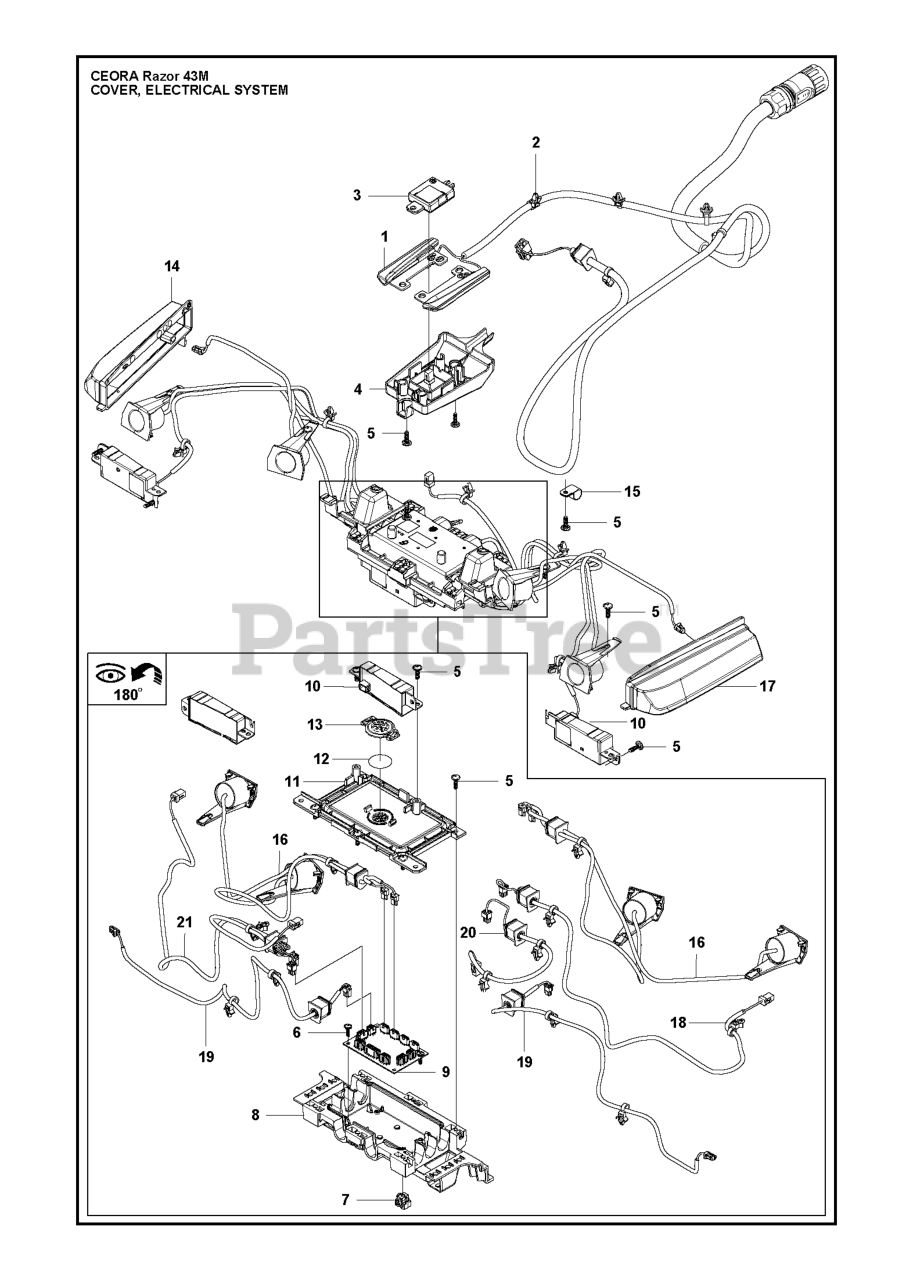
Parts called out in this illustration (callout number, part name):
1	WIRING ASSY
2	TIE WRAP CABLE TIE W ARROW MOU
3	HOUSING ASSY MAGNETIC SENSOR
4	HOLDER CHARGING PLATES
5	SCREW ITXPANT
6	SCREW 14MM
7	INSERT SCREW BLOCK
8	BASE ELECTRONIC BOX - COUPLING
9	PRINTED CIRCUIT ASSY
10	HOUSING ASSY HOUSING ASSY LOOP
11	COVER COUPLING BOX COVER WITH
12	KIT AIR FILTER KIT 305 - 10 PC
13	COVER
14	WIRING ASSY LED LIGHT FRONT RI
15	CABLE HOLDER
16	WIRING ASSY ULTRA SONIC SENSOR
17	WIRING ASSY LED LIGHT FRONT L
18	WIRING ASSY MAGNETIC & LOOP SE
19	WIRING ASSY LED LIGHT 3P FRONT
20	WIRING ASSY MAGNETIC & LOOP SE
21	WIRING ASSY MAGNETIC & LOOP SE
